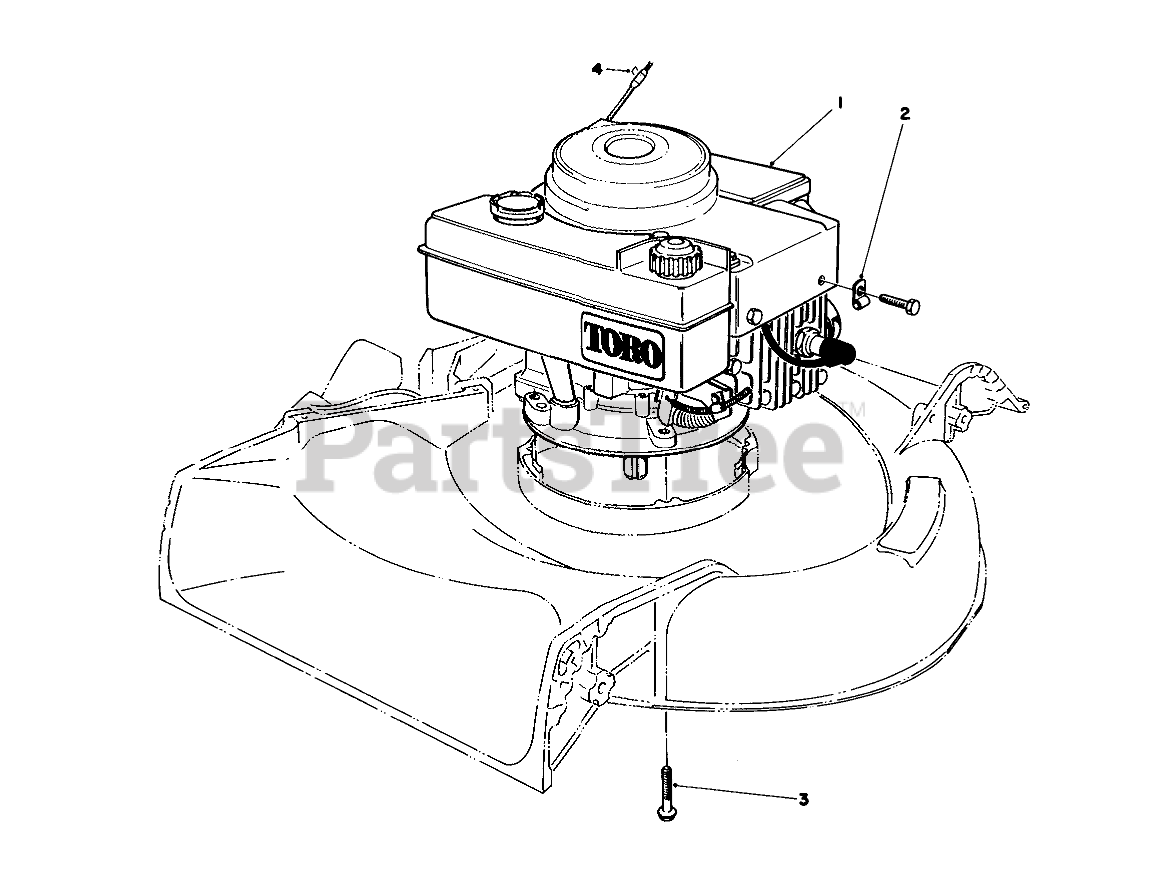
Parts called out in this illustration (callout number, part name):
2	CLAMP
3	3/8-16 X 2-3/4 CAPSCR
4	Staple
